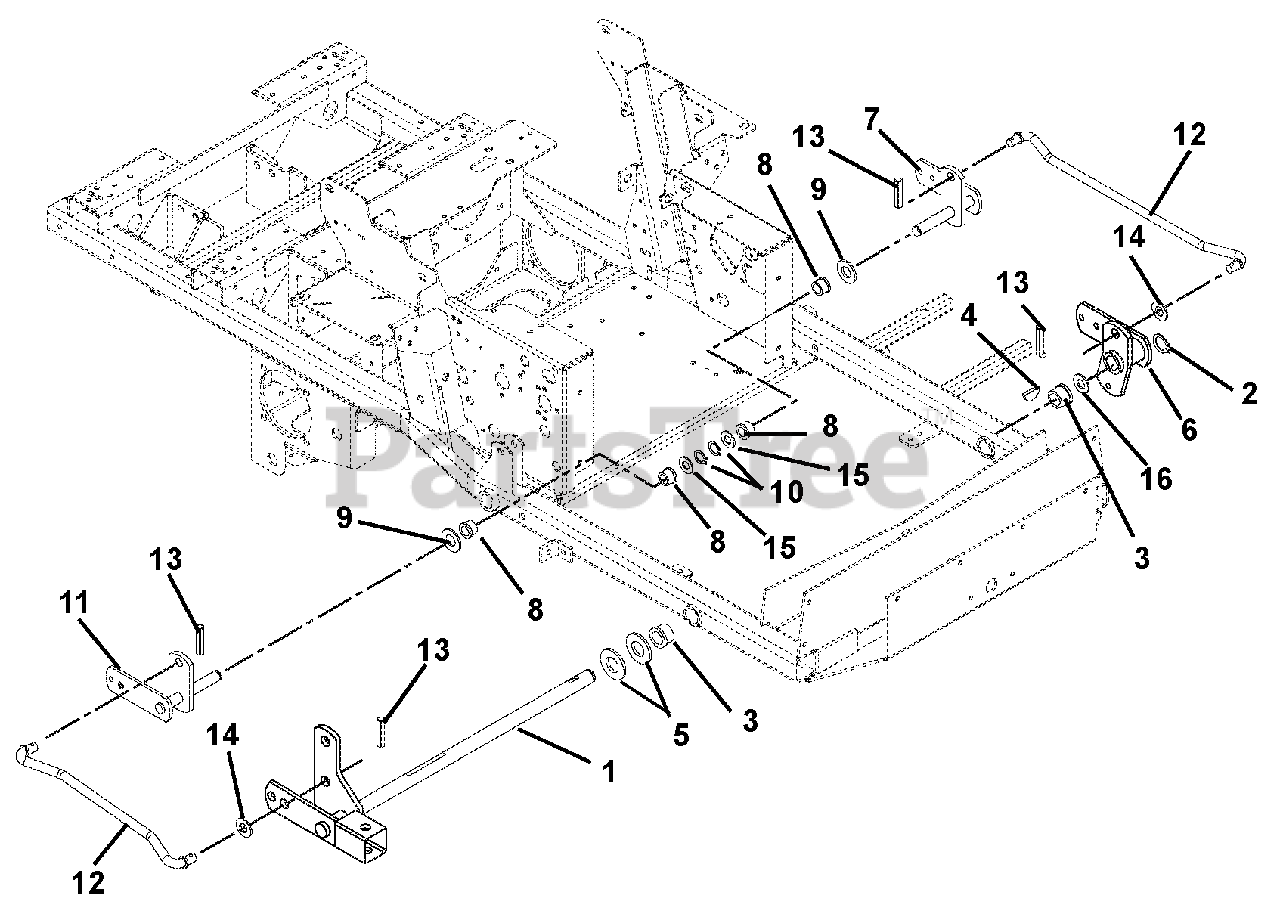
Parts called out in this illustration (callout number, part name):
1	WMT, FRONT MOWER LIFT (HYD)
2	RG-RTNG-EXT 1.00X.078
3	BSHG,1.00ID X 1.125OD X 1.50LG
4	KEY-WDRF .25X1.00 HRD #15
5	WSHR-FL-STL- 1.062X2.0X.134 YZ
6	WMT, LH FRONT MOWER LIFT
7	WMT, LH REAR DECK LIFT ARM
8	BSHG-FLG .762X1.0X.580X1.48 NY
9	WSHR-HDND-THRST .758X1.23X.031
10	RG-RTNG-EXT .689X.078
11	WMT, RH REAR DECK LIFT ARM
12	ROD-LIFT ASSIST 19.35"
13	PIN-ROLL .250X1.25 STNLESS STL
14	WSHR-FL-STL .630X1.250X.062 YZ
15	@WSHR-FL-STL.812X1.50X.135YWZC
16	WSHR-HDND-THRUST 1.00X1.55X.03
